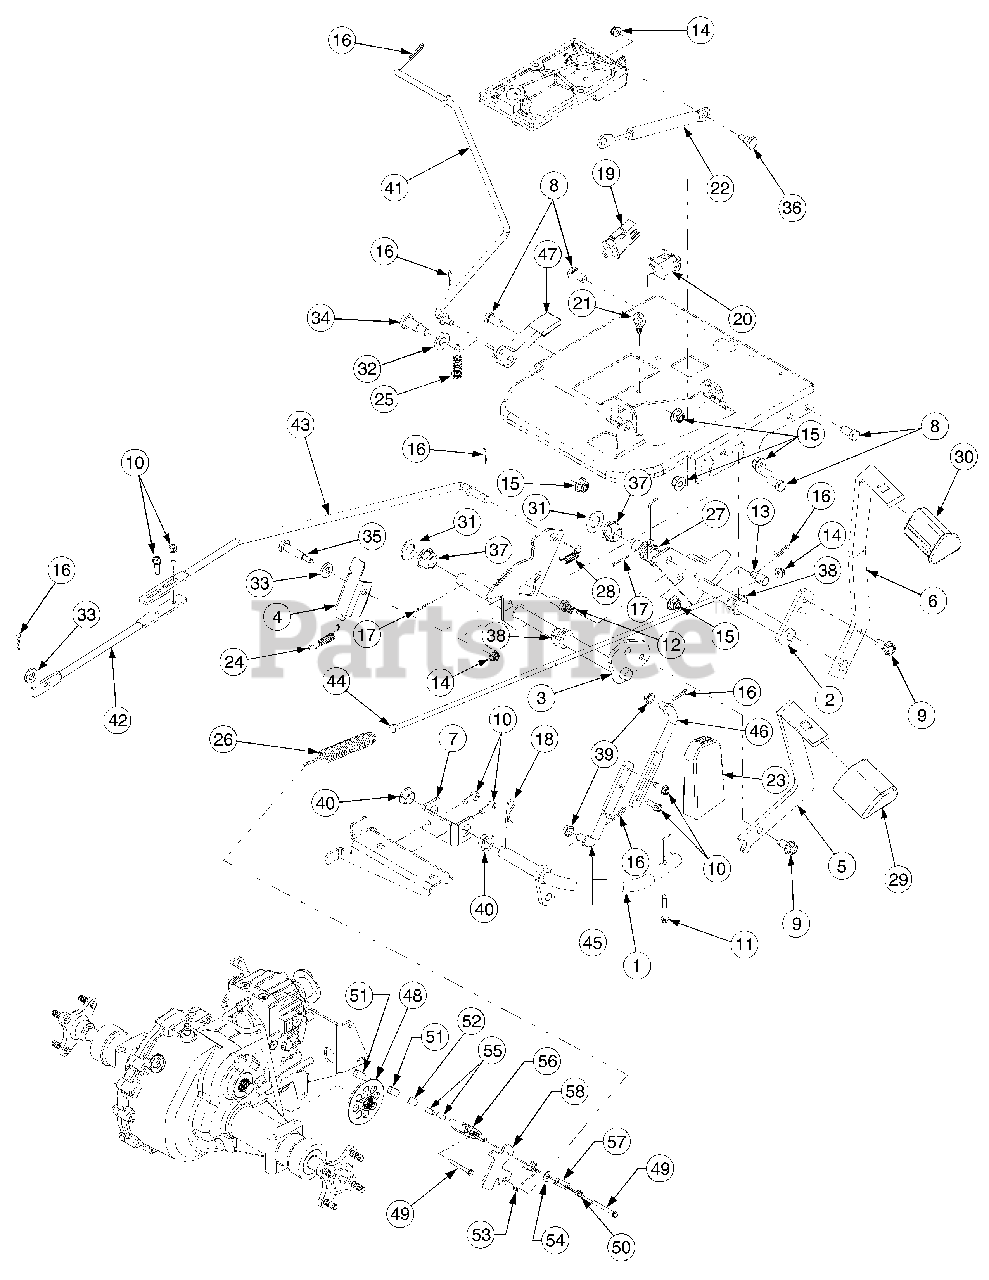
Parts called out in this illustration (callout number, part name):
3	Shaft Assy, Forward/Reverse
8	Screw, Hex Cap, 3/8-16 x 1.0 GR5
9	Screw, Hex Wash Hd Tapp 3/8-16x .75
10	Screw, Hex Wash Hd Tapp 1/4-20x .75
11	Screw, Truss Mach, #12 x 1.5
12	Pin, 3/8-16 x 1.0
13	Ferrule, Adjustment, 1/4-20 Thrd
14	Nut, Hex Flange Lock, 1/4-20
15	Nut, Hex Flange Lock, 3/8-16
16	Pin, Internal Cotter, 5/16 Dia x 1.12
17	Pin, Cotter, 3/32 x 1.0
18	Pin, Internal Cotter, 3/8 Dia x 1.62
19	Switch, Interlock (Brake)
20	Switch, Snap Mount (Reverse)
21	Clip, Cable Retainer
22	Cylinder, Damper, .59 OD x 7.84 Lg
23	Pedal, Reverse
24	Spring, Extension, .38 OD x 2.1
25	Sping, Extension
26	Spring, Extension
27	Spring, Torsion
28	Spring, Extension, .375 OD x 1.44
29	Pad, Forward Foot Control
30	Pad, Brake Foot
31	Washer, Flat, .64 x 1.24 x .06 HT
32	Washer, Flat, .51 x 1.0 x .125
33	Washer, Flat, .407 x .812 x .135 HT
34	Shoulder Bolt, .50 OD x .840
35	Screw, Shoulder, .374 x 1.375
36	Screw, Shoulder, .375 x .380:1/4-20
37	Bearing, Hex Flange
38	Bearing, Hex Flange Split
39	Bearing, Flange, .375 x .58 x .25
40	Bearing, Flange, .625 x .938 x .344
41	Rod, Cruise
42	Rod, Rear F/R Control
43	Rod, Front F/R Control
44	Rod, Brake
45	Rod, Rear Connecting
46	Rod, Front Connecting
47	Latch, Cruise
48	Disc, Brake
49	Screw, Hex Wash Hd, Tapp, 1/4-20 x 2.375
50	Nut, Hex Nylon Lock, 5/16-24
51	Pad, Brake
52	Plate, Puck
53	Spring, Torsion
54	Washer, Flat, .343 x .88 x .062
55	Pin, Brake Actuating
56	Yoke, Brake
57	Bracket, Brake Anti Rotation
58	Arm, Brake Actuator
